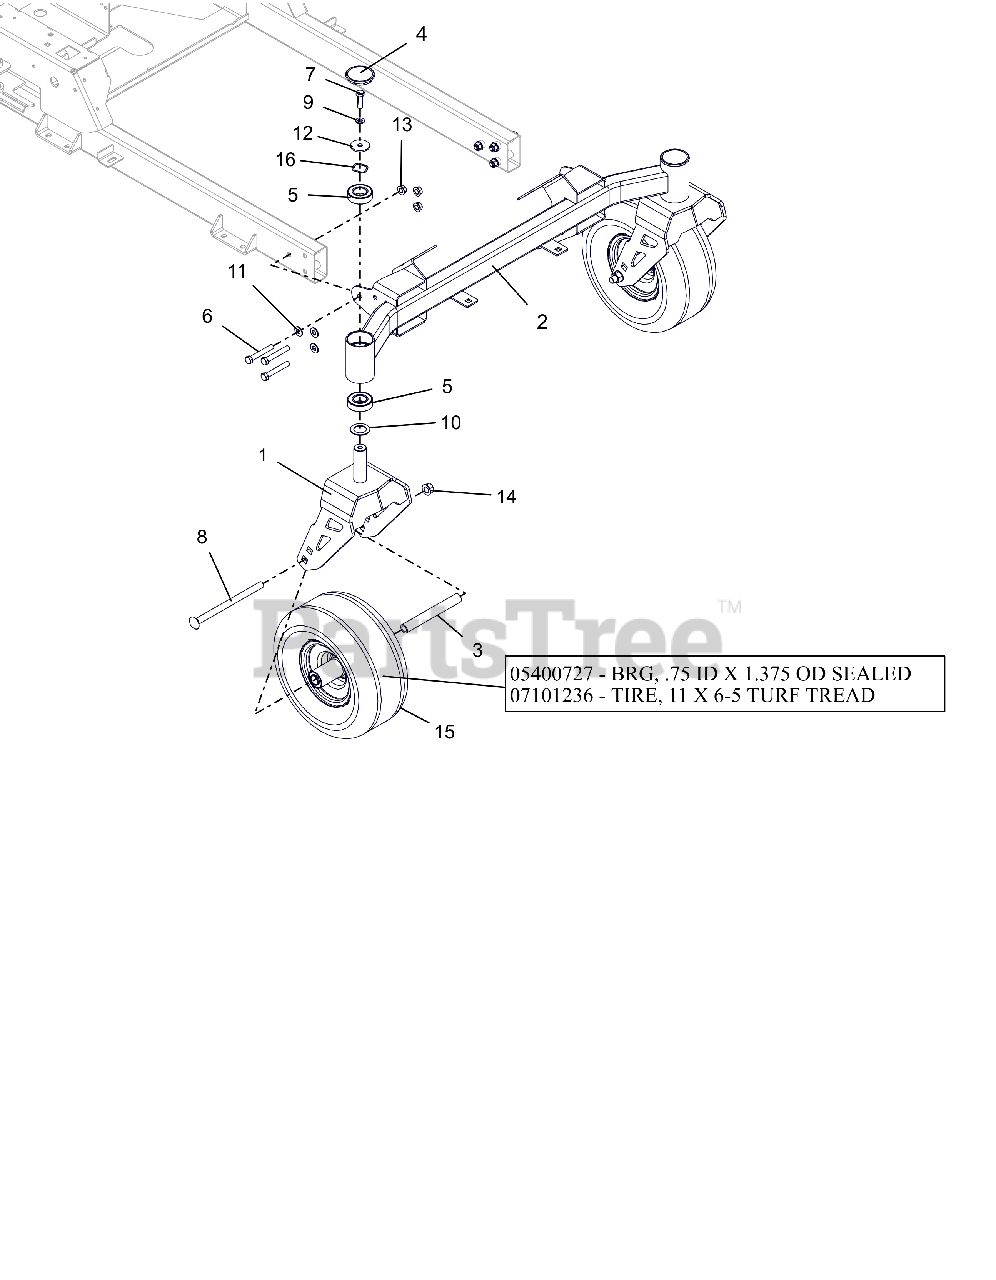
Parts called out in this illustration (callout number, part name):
1	WLDMT, CASTER FORK (WIDE)
2	WLDMT, AXLE FRONT
3	SPACER, FRONT WHEEL (WIDE 6.0)
4	CAP, DUST
5	BRG,BALL 1.00X2.00X.563(1641)
6	BLT-HEX .38-16X2.50 GR8 YWZC
7	@BLT-HEX .38-16X1.25 GR5 YWZC
8	@BLT-RDHDSQNK .50-13X7.50 G5YZ
9	@WSHR-LK .38X.094 REG YWZC
10	WSHR-HRD-THRS 1.007X1.542X.062
11	WSHR-HDND .406X.812X.055
12	WSHR-FL-STL .380X1.50X.125YWZC
13	NUT-LK-TOP-FLG .38-16 GRG YWZC
14	@NUT-LK-TOP-FLG .50-13 YWZC
15	TIRE/WHEEL ASSY, 11X6-5
15	BRG, .75 ID X 1.375 OD SEALED
15	TIRE, 11X6-5 TURF TREAD
16	WSHR-WAVE 1.0X1.25X.028 .145FH
